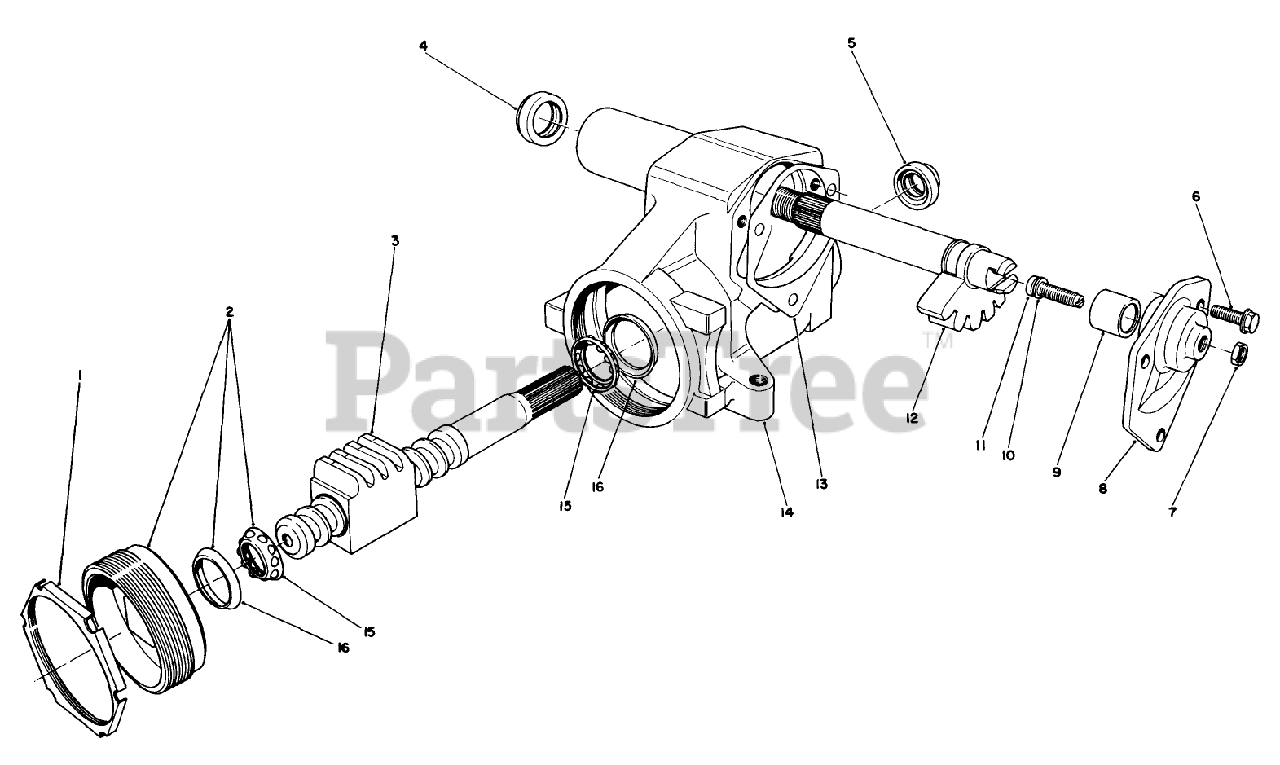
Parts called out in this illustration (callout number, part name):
1	Nut-Adjuster Lock
2	Assembly-Adjuster
3	Steering Worm Assembly
6	Bolt-Flange Hex. Hd.
8	Kit-Service, Side Cover (Incl. Ref. #6, 9, 11 & 13)
10	Kit-Shim
11	Adjuster
12	Gear-Pitman Shaft
13	Gasket
14	Housing-Steering Gear
15	Assembly-Thrust Bearing
16	Cup-Bearing
